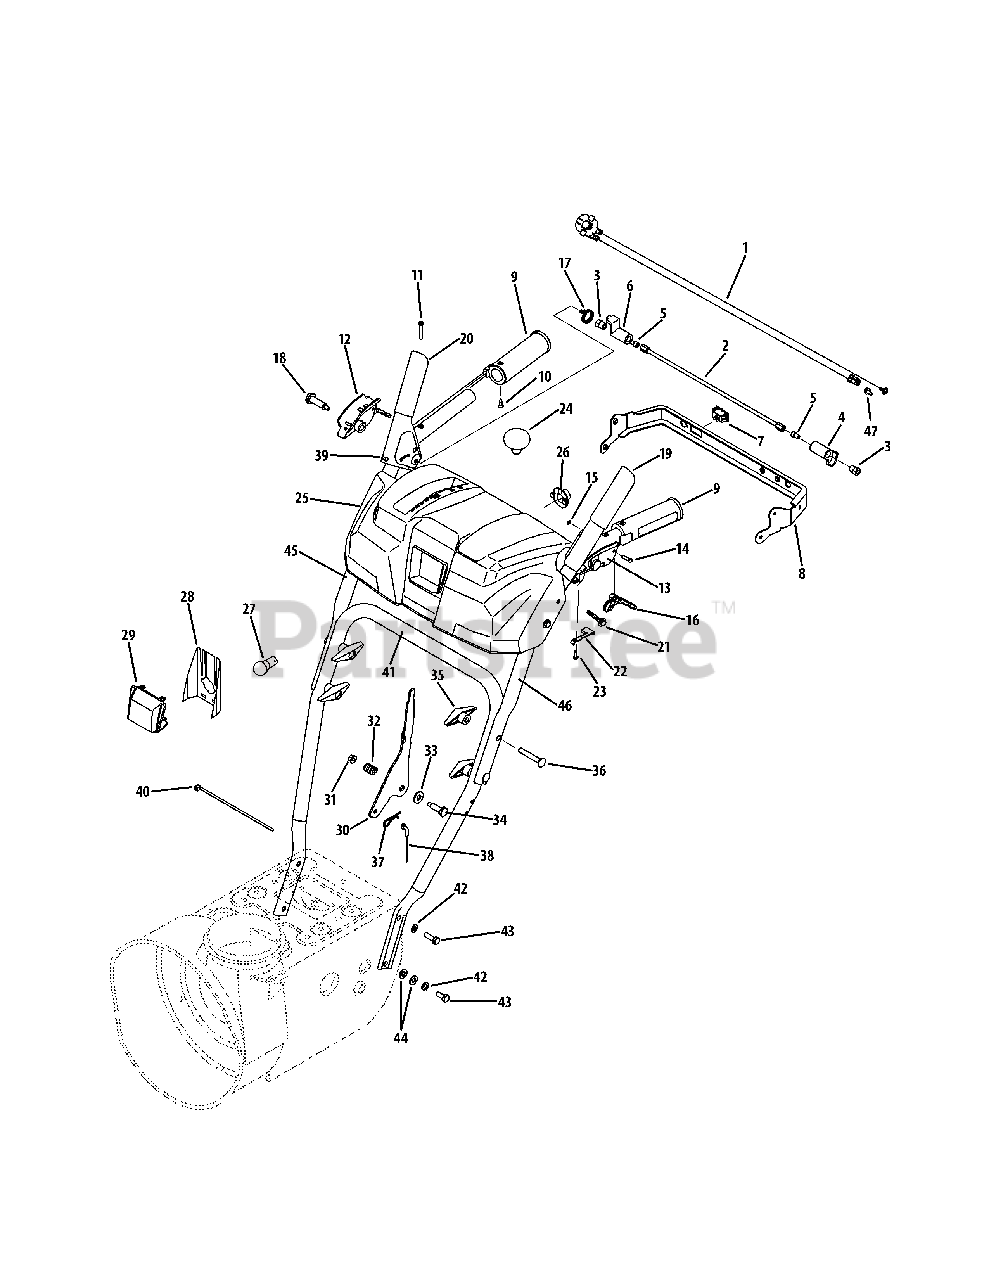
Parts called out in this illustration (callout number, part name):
1	Wire Harness
2	Clutch Lock Rod Assembly
3	Hex Shoulder Nut, 1/4-20
4	Clutch Lock Cam
5	Socket Cap Screw 1/4-20 x .50
7	Heated Grip Switch
8	Panel Bracket
9	Heated Grip
10	AB Screw, #10-16 x .625
11	Machine Screw, #10-24 x 1.375
12	Clutch Lock Handle Assembly, RH
13	Clutch Lock Handle Assembly, LH
15	E-Type Ring, .375
16	Clutch Trigger Lock
17	Torsion Spring, .8156 ID x .3038
18	Shoulder Screw, .437 x 1.345 x 1/4-20
19	Engagement Handle Assembly, LH
20	Engagement Handle Assembly, RH
21	Hex Washer Screw, 1/4-20 x 1.625
22	Clutch Lock Spring
23	Hex Washer Screw, #8-16 x .50
24	Shift Knob
25	Handle Panel
26	Light Socket
27	Lamp
28	Lens Label
31	Flange Lock Nut, 1/4-20
32	Compression Spring, .39 x .60 x .88
33	Flat Washer, .385 x .87 x .06
34	Shoulder Screw, .374 x 1.05
35	Knob Assembly, 5/16-18
36	Carriage Screw, 5/16-18 x 2.25
37	Click Pin, .092 x 1.64
38	Speed Selector Cable
39	Rubber Bumper, .62 x .22
40	Cable Tie, 3/16 x .05 x 7.43
42	Lock Washer, 5/16
43	Hex Bolt, 5/16-18 x .75
44	Flat Washer, .344 x .688 x .065
45	Upper Handle, RH
46	Upper Handle, LH
47	Screw, 1/4-20 x .500
